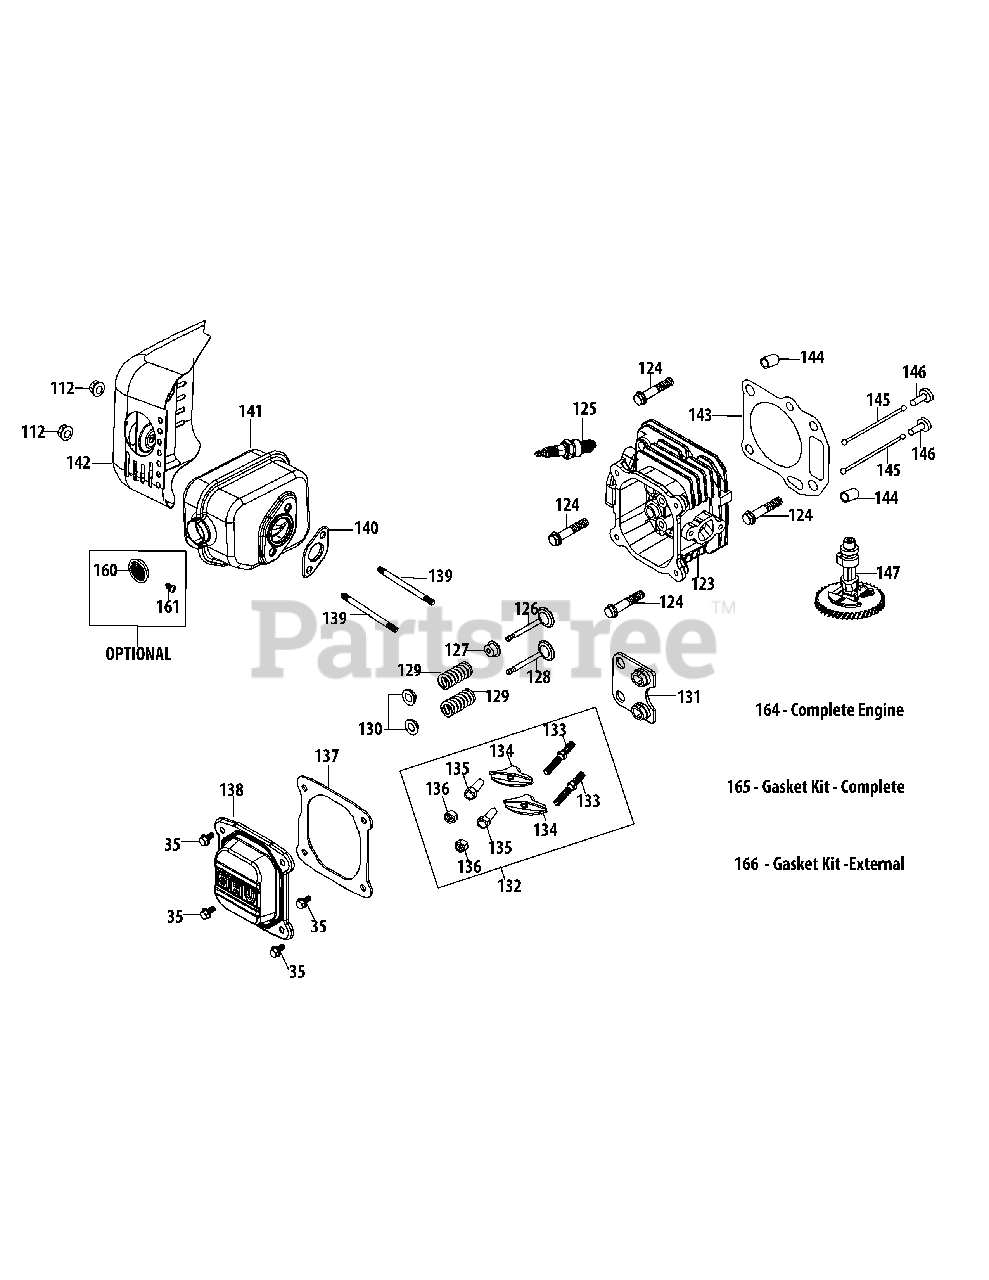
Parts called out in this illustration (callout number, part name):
35	Bolt M6X14 Multi-Purpose
112	Nut M6X10Mm Starter/Carb/Muff
123	Cylinder Head Asm
123	Cylinder Head Service Kit
124	Bolt M8X54 Cylinder Head
125	Spark Plug/F5Rtc
126	Valve Kit
127	Intake Valve Seal
128	Valve Kit
129	Valve Spring
130	Valve Spring Retainer
131	Push Rod Guide
132	Rocker Arm Assembly
133	Rocker Arm Stud
134	Rocker Arm
135	Fulcrum Nut
136	Jam Nut
137	Valve Cover Gasket
138	Valve Cover
139	Muffler Stud M6X95
139	Muffler Stud Assembly
140	Muffler Gasket
141	Muffler Assembly
142	Muffler Shield
143	Cylinder Head Gasket
144	Cylinder Head Dowel Pin F10×16
145	Push Rod
146	Tappet
147	Camshaft Assembly
160	Spark Arrestor
161	Spark Arrestor Screw
164	Complete Engine
165	Gasket Kit - Complete
166	Gasket Kit -External
